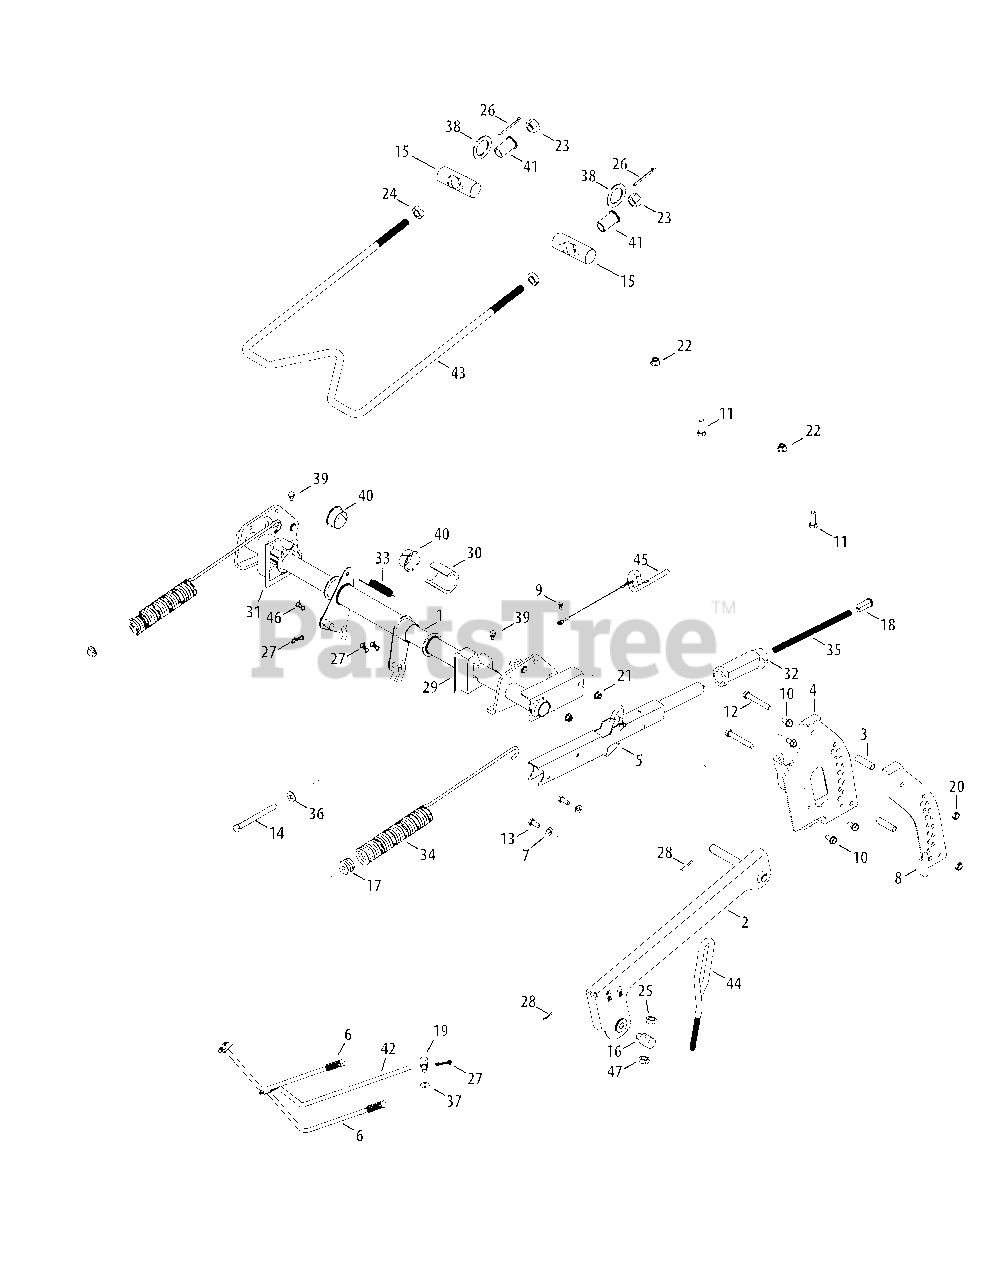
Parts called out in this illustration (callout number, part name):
1	Deck Lift Shift Assembly
3	Spacer, .386 x .63 x 1.75
4	Index Bracket Assembly
5	Latch Handle Assembly
6	Brake Rod Assembly
7	Flat Washer .330 ID x .630 OD
8	Outer Index Bracket
9	Screw, #10-16, .50
10	Hex Washer Screw, 5/16-18 x .750
11	Hex Screw, 3/8-16 x 1.00
12	Hex Head Screw, 3/8-16 x 2.50
13	Hex Cap Screw, 5/16-18 x .75
14	Hex Screw, 3/8-16 x 4.25
15	Pivot Pin, 1.25
16	Ferrule, .496 x .528
17	Spring Insert
18	Handle Button
19	Ferrule, 3/8-24 x .375
20	Jam Lock Nut, 3/8-16
21	Flange Lock Nut, 5/16-18
22	Flange Lock Nut, 3/8-16
23	Nylock Nut, 5/8-11
24	Jam Nut, 5/8-11
25	Nut, Jam, 1/2-13
26	Cotter Pin, 3/16 x 2.0
27	Bow-Tie Cotter Pin
28	Cotter Pin 1/8 x 1.25
29	Deck Lift Bracket
30	Spacer, 1.375 Shaft
31	Deck Lift Bracket, LH
32	Grip, Deck Lift Handle
33	Extension Spring, .63 Dia. x 4.95 LG
34	Extension Spring, 1.485 OD x 17.58
35	Spring, Compression, .4 x 8.52
36	Flat Washer, .385 x .870 x .092
37	Washer, .375 x .700 x .030
38	Flat Washer, 1.875 x 1.38 x .097
39	Shoulder Screw, .500 x 1/4-20
40	Flange Bearing, 1.38 x 1.75 x .50
41	Flange Bearing, .875 x .702 x 1.10
43	Deck Hanger Rod, 5/8
44	Lift Adjust Link
45	Lock Rod, .375
46	Bow-Tie Cotter Pin
47	Hex Nut, 1/2-13
